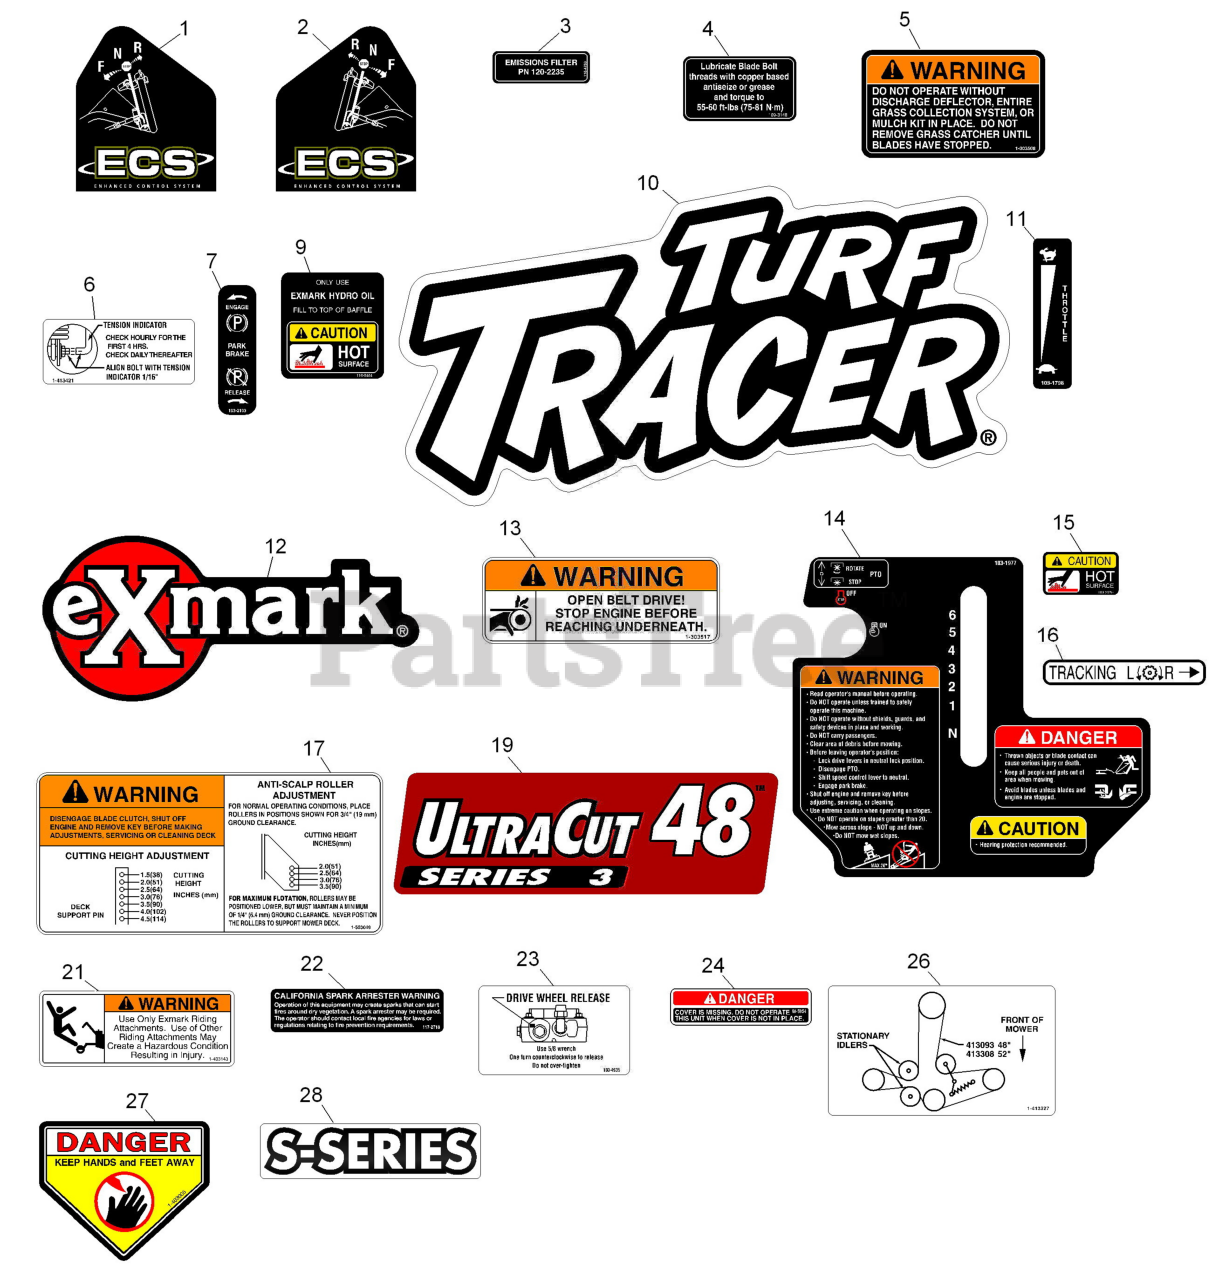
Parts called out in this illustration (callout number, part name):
1	DECAL,LH ECS INSTRUCTION
2	DECAL,RH ECS INSTRUCTION
3	DECAL-FILTER, EMISSIONS
4	DECAL,BOLT TORQUE
5	DECAL-WARNING, DISCHARGE
6	DECAL,INDICATOR
7	DECAL-BRAKE, PARK
9	DECAL-HYDRAULIC TANK
10	DECAL,TTH MODEL
11	DECAL,THROTTLE ONLY
12	DECAL,EXMARK LOGO
13	DECAL,BELT DRIVE
14	DECAL,ECS CONSOLE
15	DECAL-CAUTION
16	DECAL,TRACKING ADJUST
17	DECAL,ANTI SCALP
19	DECAL-ULTRACUT 48 SERIES
21	DECAL,SULKY WARNING
22	DECAL-ARRESTER, SPARK
23	DECAL,DRIVE RELEASE
24	DECAL-COVER, MISSING
26	DECAL,BELT ROUTING
27	DECAL-DANGER
28	DECAL-S-SERIES
